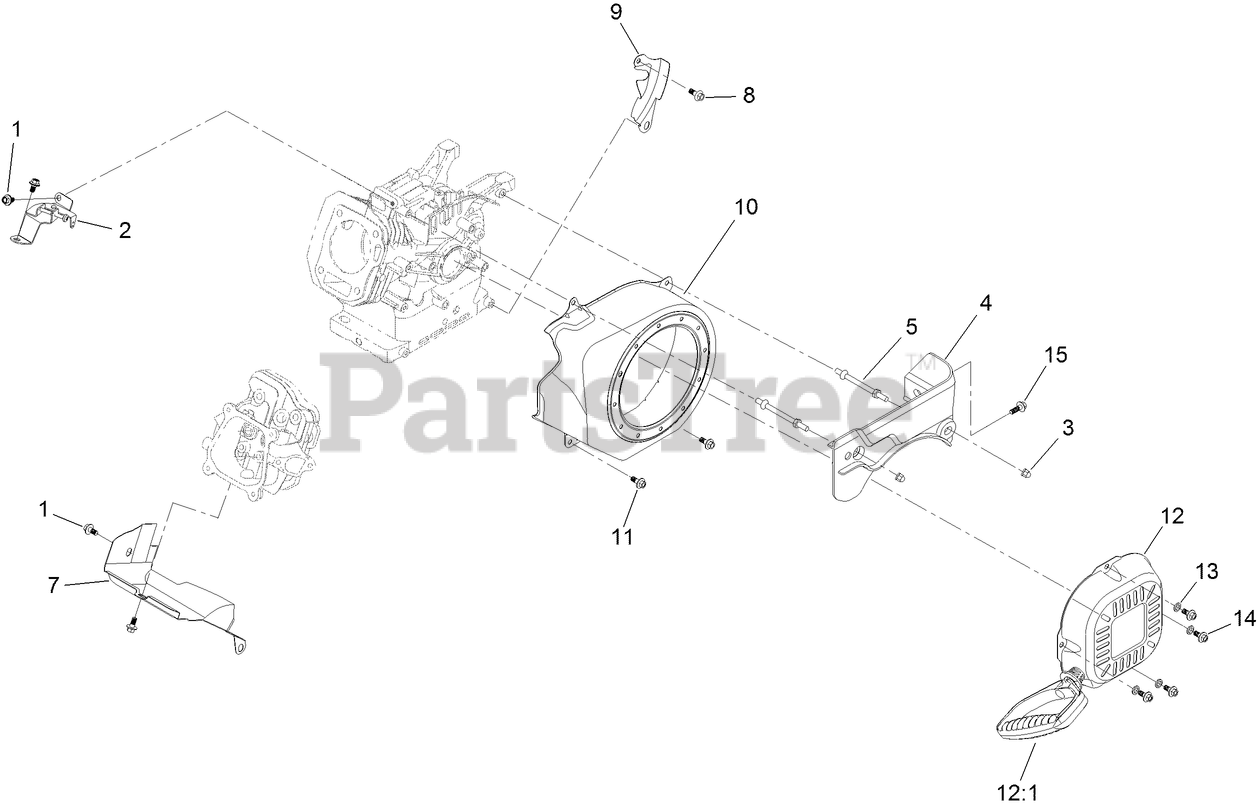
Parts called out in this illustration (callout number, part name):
1	SCREW-HHF
2	SPEED CONTROL ASM
3	NUT-ACORN
4	PANEL-FRONT
5	STUD-MOUNT
7	SHROUD-LOWER
8	SCREW-HHF
9	SHIELD-FLYWHEEL
10	SHROUD-BLOWER
11	SCREW-HHF
12	RECOIL STARTER ASM
12:1	HANDLE-RECOIL
13	WASHER-PLAIN
14	SCREW-HHF
15	SCREW-HHF
